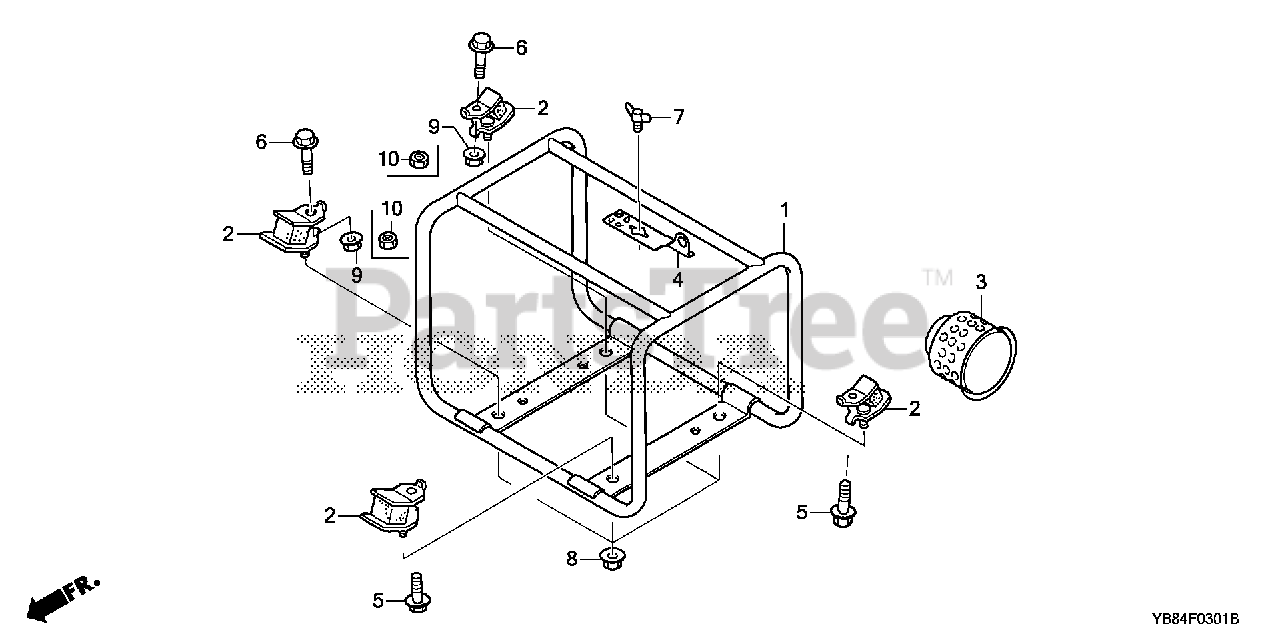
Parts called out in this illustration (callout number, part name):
2	RUBBER (LOWER)
5	BOLT-WASHER (12X45)
6	BOLT-WASHER (8X35)
7	BOLT, WING (8X15)
8	NUT-WASHER (8MM)
9	NUT, FLANGE (8MM)
